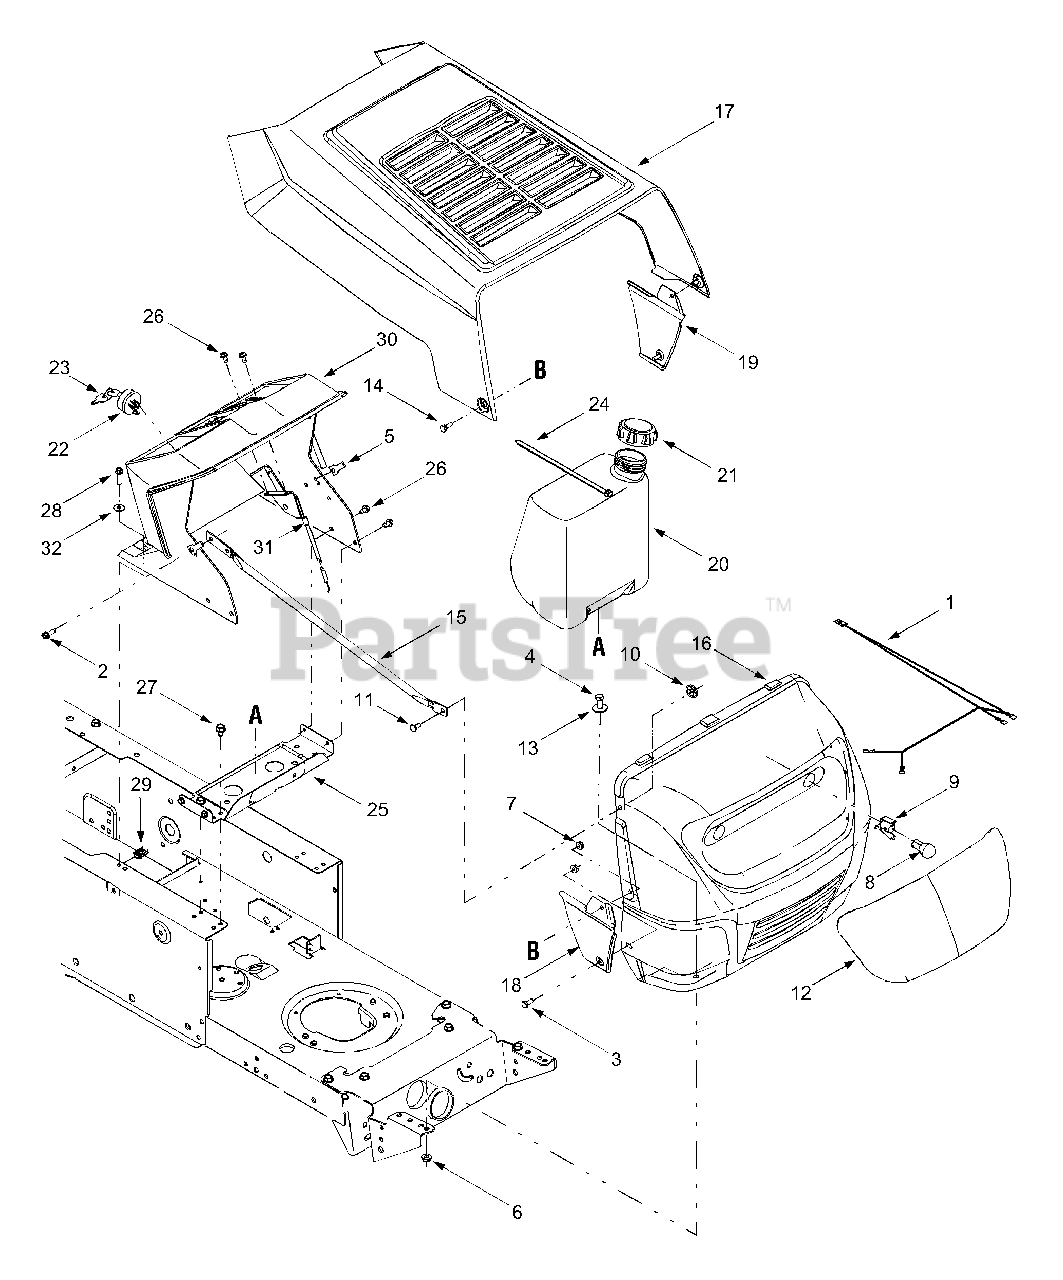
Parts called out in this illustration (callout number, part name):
1	Headlamp Harness Assembly
2	Self-tapping Screw, 1/4-20 x .75
3	Hex Screw, 1/4-20 x .620
4	Hex Screw, 5/16-18 x .75
5	U-type Speed Nut, 1/4-20
6	Flange Lock Nut, 5/16-18
7	Flange Lock Nut, 1/4-20
8	Headlamp, 12V
9	Headlamp Socket
10	Push-on Nut, .25
11	Flat-head Rivet, 1/4
12	Lens
13	Flat Washer, .344 x 1.0 x .063
14	Shoulder Screw, 1/4-20 x .375 /.125
21	Fuel Tank Cap
22	Ignition Switch, 6-pin
23	Keys (pair)
24	Cable Tie, 30.66
25	Battery Support Bracket
26	Self-tapping Screw, 1/4-20 x .5
27	Self-tapping Screw, 5/16-18 x .5
28	Self-tapping Screw, 1/4-20 x 1.0
29	U-type Speed Nut, 1/4-20
30	Dash Panel
31	Throttle / Choke Control, 18.5"
32	Flat Washer, .260 x .720 x .060
